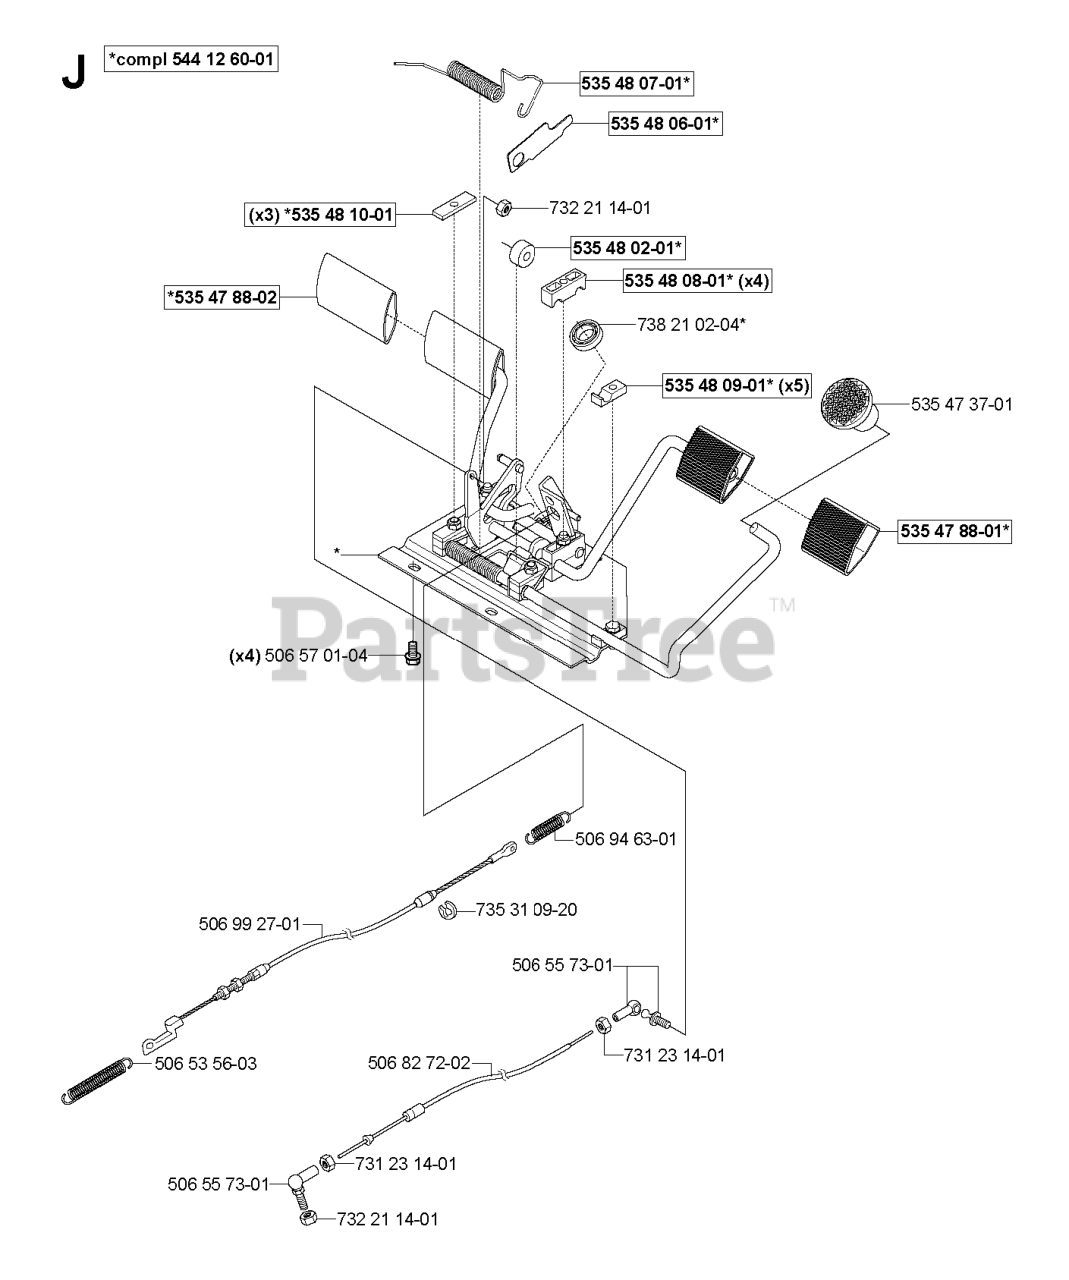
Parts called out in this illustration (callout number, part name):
1	DECK.SVC.48.CC.ASM.668
2	MANDREL ASM, CAST IRON
3	WASHER.SPACER.MANDREL
4	MANDREL PULLEY
7	GSPW Deflectors
8	SPRING.42.FCS.DEFLECTOR
10	BLADE.BAGGER.RES.CLRCT.48".BLK
11	BOLT.WASHER.ASM.7/16-2
15	STUD.W/"D"ANTI-ROTATION
16	NUT HEXAGON FLANGE 5/16-18 ST
17	PULLEY.IDLER.MWR.STATI.LH
18	ARM.PNT.CLUTCHING.EDIP
19	PULLEY.IDLER.48"PRIMARY
22	WHEEL.GAUGE.RALLY
26	SCREW.7/16-14 X 2.125.WASHER
31	NUT LOCK FLG 3/8-16 UNC
36	ARM.RFIXED.MOWER.SUSPNSIONX431
39	GSPW Nuts
40	NOSE ROLLER 48"
42	PIN.COTTER.5/16.BOW TI
50	PORT.WASHOUT
54	GUARD, BELT
55	GSPW Bolts
56	GSPW Hardware
57	SPRING.EXTN.42.FCS.TR.DECK.DRV
64	BOLT.HEX.WASHR.HED.313-18X1.19
67	PULLEY.IDLER.2006
68	BOLT;HEX_3/8-16 X 1.78.CLRZINC
69	BOLT.SHOULDER
71	NUT PUSH M
73	COVER.PNT.MANDREL.RH.GREY
74	SCREW.1/4-20X5/8
75	COVER.PNT.MANDREL.LH.TR.GREY
76	BUMPER 48 CLEARCUT TRIM SIDE A
77	BUSHING.NOSE.ROLLER
80	SHOULDER BOLT 5/16-18TT
81	CAP-SLEEVE LT
